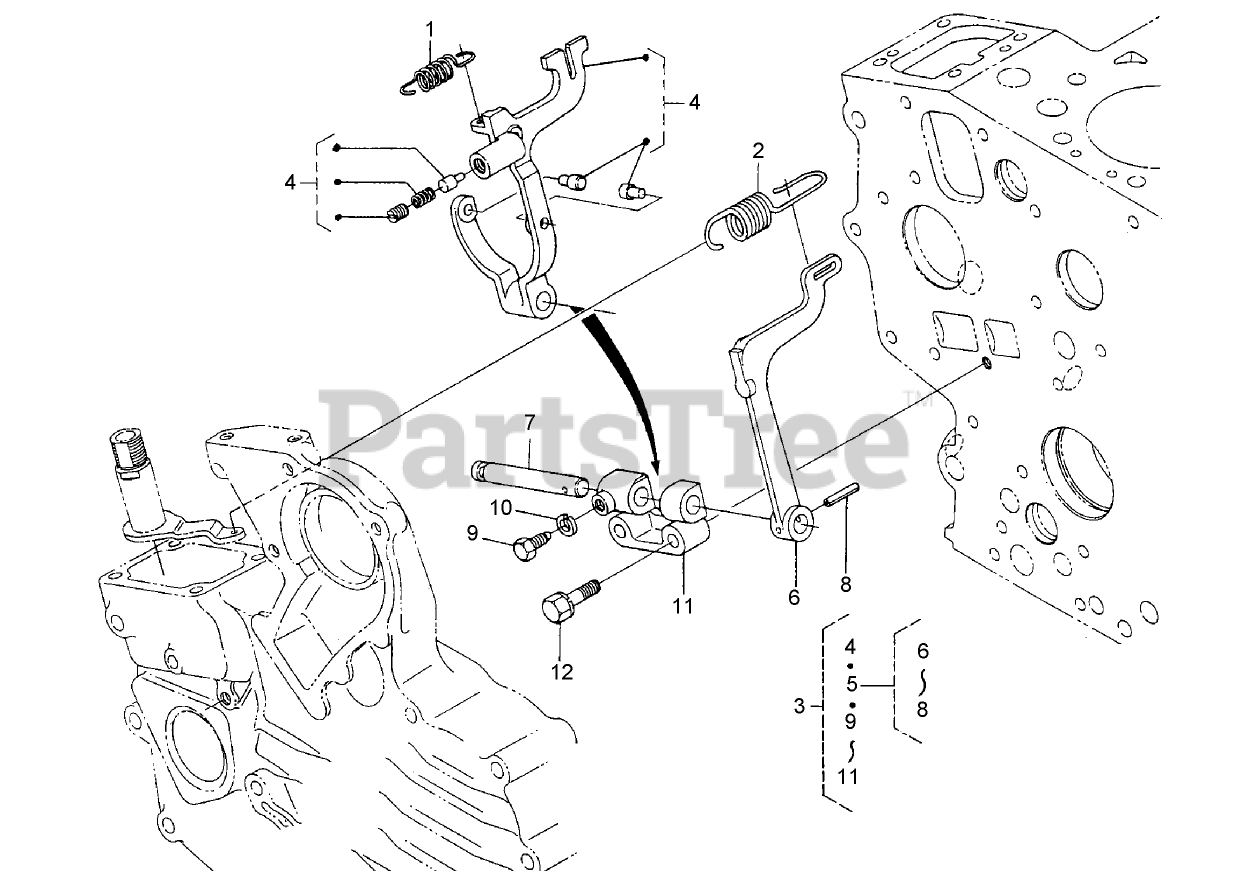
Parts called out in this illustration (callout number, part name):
1	SPRING-START
2	SPRING-GOVERNOR
3	FORK LEVER ASM
4	LEVER-FORK
5	FORK LEVER ASM
6	LEVER-FORK
7	SHAFT-LEVER, FORK
8	PIN-SPRING
10	WASHER-SPRING
11	HOLDER-LEVER, FORK
